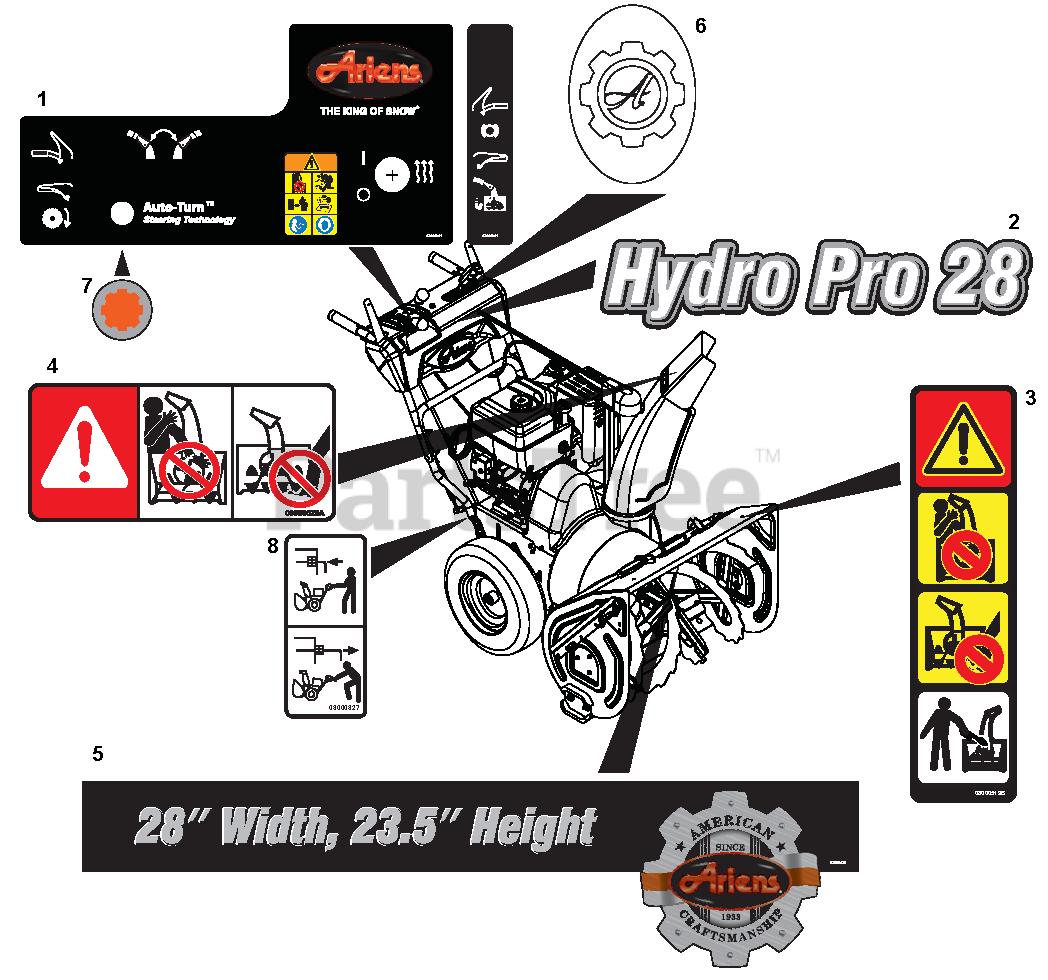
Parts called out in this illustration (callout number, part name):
1	DECAL, CONTROL PLATINUM/PRO
2	DECAL, PRO HYDRO 28 DASH
3	DECAL, DANGER - ROTATING PARTS
4	DECAL, DANGER
6	DECAL, ARIENS GEAR - RAISED
7	DECAL,AUTODIFFERENTIAL
8	DECAL, BYPASS
